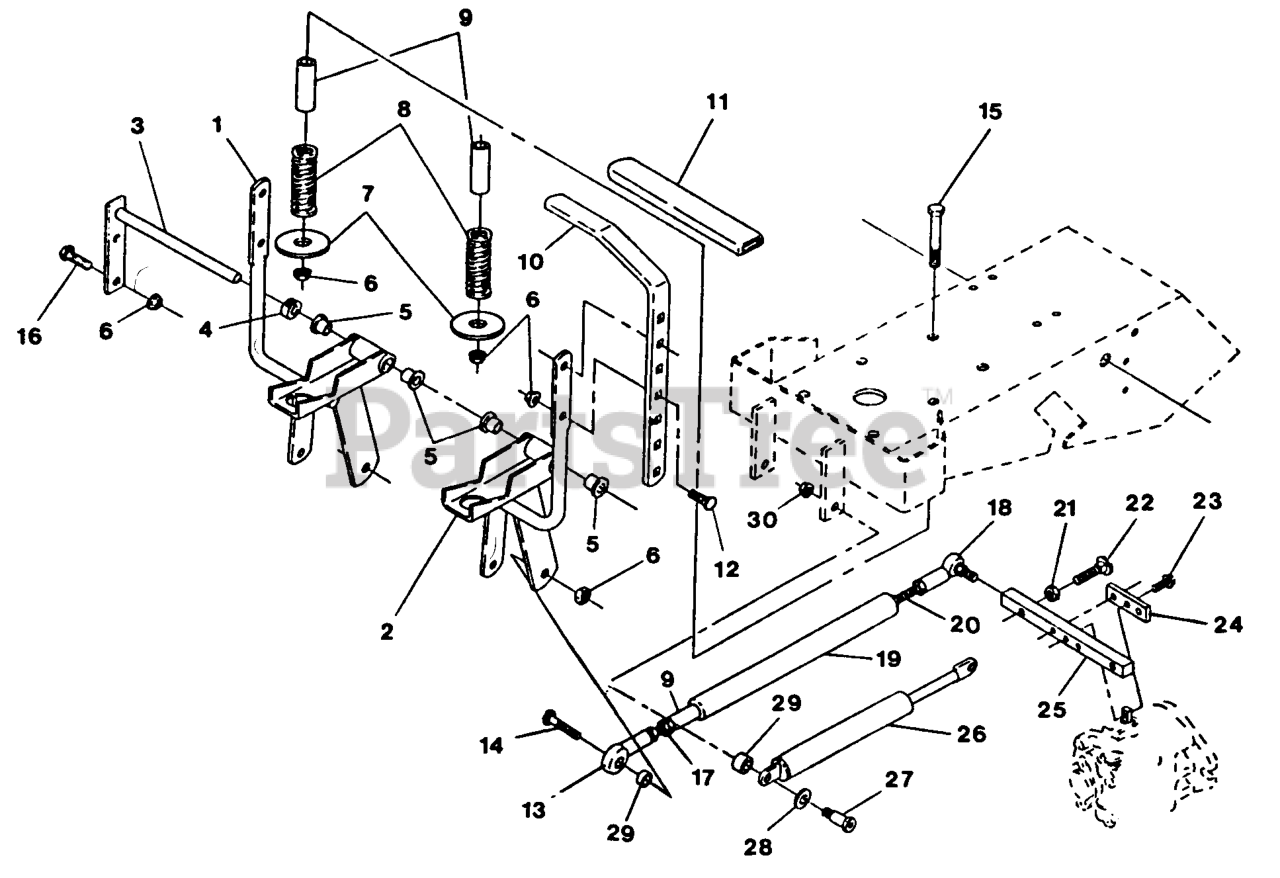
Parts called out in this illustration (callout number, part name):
5	BEARING-CONTROL
7	SCREEN,PERFORATED RH PNT
8	SPRING-INDICATOR, REVERSE
9	BUSHING,SPRING GUIDE
13	BALLJOINT-RH
18	BALLJOINT
20	ROD,STEERING
24	PLATE,CLAMP
25	ARM,PUMP CONTROL
29	SPACER-PLATED
